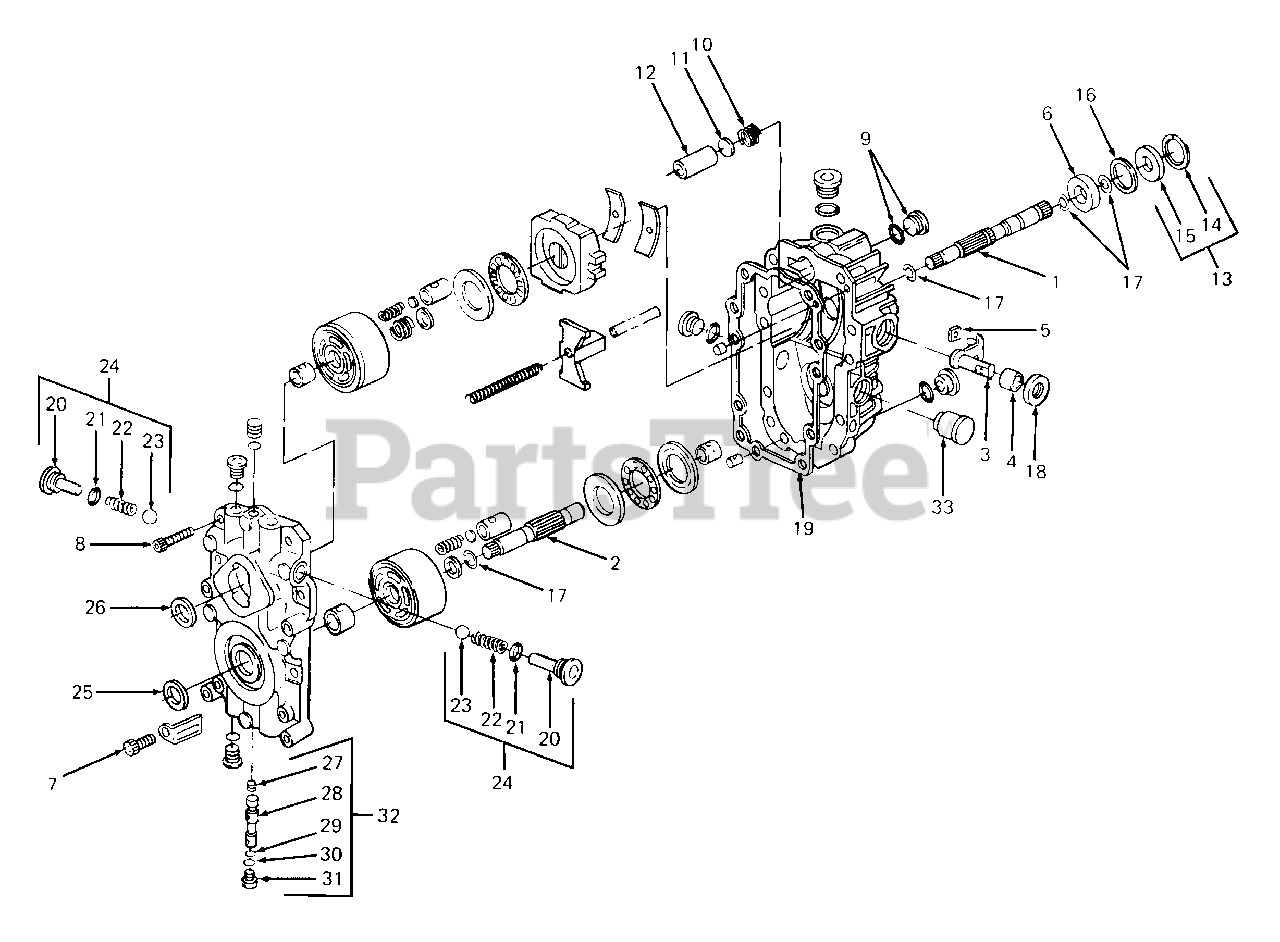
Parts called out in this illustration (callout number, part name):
1	Shaft - Pump
2	Shaft - Motor
3	Arm, Trunnion
4	Bearing, Journal
5	Guide, Slot
6	Bearing, Ball
7	Screw, Socket Head
8	Screw, Socket Head
9	Plug
10	Spring, Filter
11	Washer, Filter
12	Filter
13	Kit, Seal
14	Ring, Retaining
15	Seal, Lip
16	Spacer
17	Ring, Retaining
18	Seal, Lip
19	Gasket
20	Plug, Check Valve
21	O-Ring
24	Kit, Check Valve
25	Seal, Lip
26	Seal, Lip
27	Spring
28	Spool, Bypass
29	O-Ring
30	O-Ring
32	Kit, Bypass Valve
33	Reservoir
